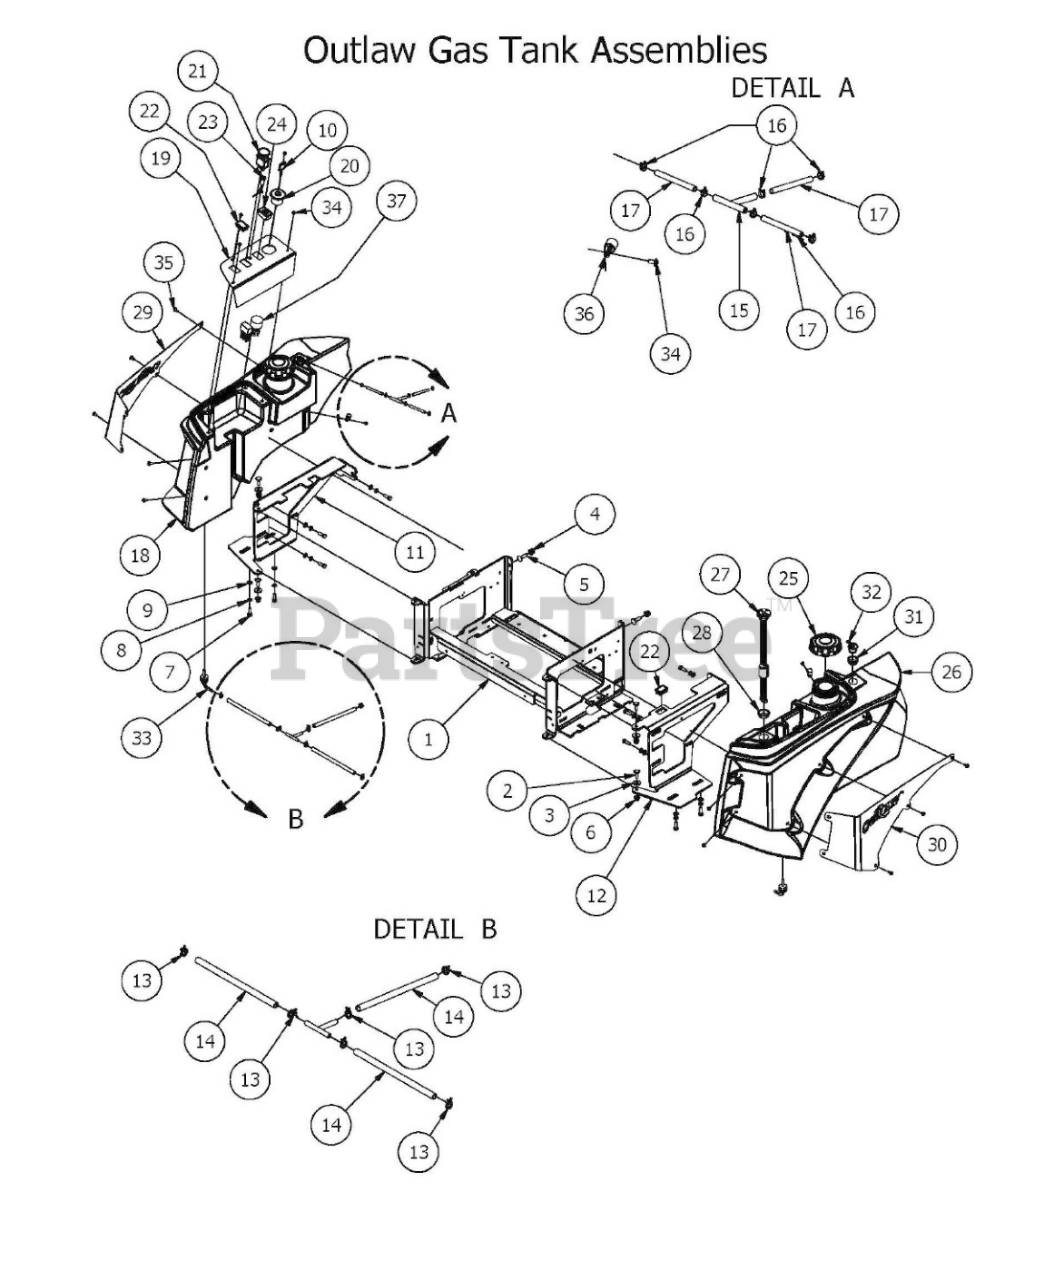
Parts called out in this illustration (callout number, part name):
1	2017 Outlaw Seat Bracket
2	5/16-18 x 1 Carriage Bolts Zinc
3	.360 ID Plastic Washer
4	3/8" Nylock Flange Nut
5	3/8" x 1 1/4" Carriage Bolt
6	5/16-18 Nylon Insert Flange Nut Zinc Orange Nylon
7	5/16" x 1" Bolt
8	5/16" Lock Washer
9	5/16" Flat Washer
10	Ignition Key
11	Outlaw 2015 Tank Support (Right)
12	Outlaw 2016 Tank Support (Left)
13	1/4 Fuel Hose Clamp
14	1/4" Fuel Line Hose
15	fuel line T
16	3/16 Vinyl Clamp
17	1/4" Vinyl Tubing
18	Outlaw 2015 Fuel Tank (Right)
19	Analog Control Panel Outlaw
20	Ignition Switch
21	PTO Switch
22	Light Plug
24	Tachometer
25	Fuel Cap (Kelch)
26	Outlaw 2015 Fuel Tank (Left)
27	Fuel Gauge w/Grommet
28	Grommet for Fuel Gauge
29	Outlaw Tank Panel (Right)
30	Outlaw Tank Panel (Left)
31	ROV Grommet
32	Rollover Valve - Black
33	Fuel Tank Hose Nipple w/Filter
34	10-32 x 3/8" Button Socket Head Bolt
35	1/4" x 1/2" BS C/S 18-8 SS
36	3/8 Cable Clamp-Black Nylon
37	Wiring Harness
